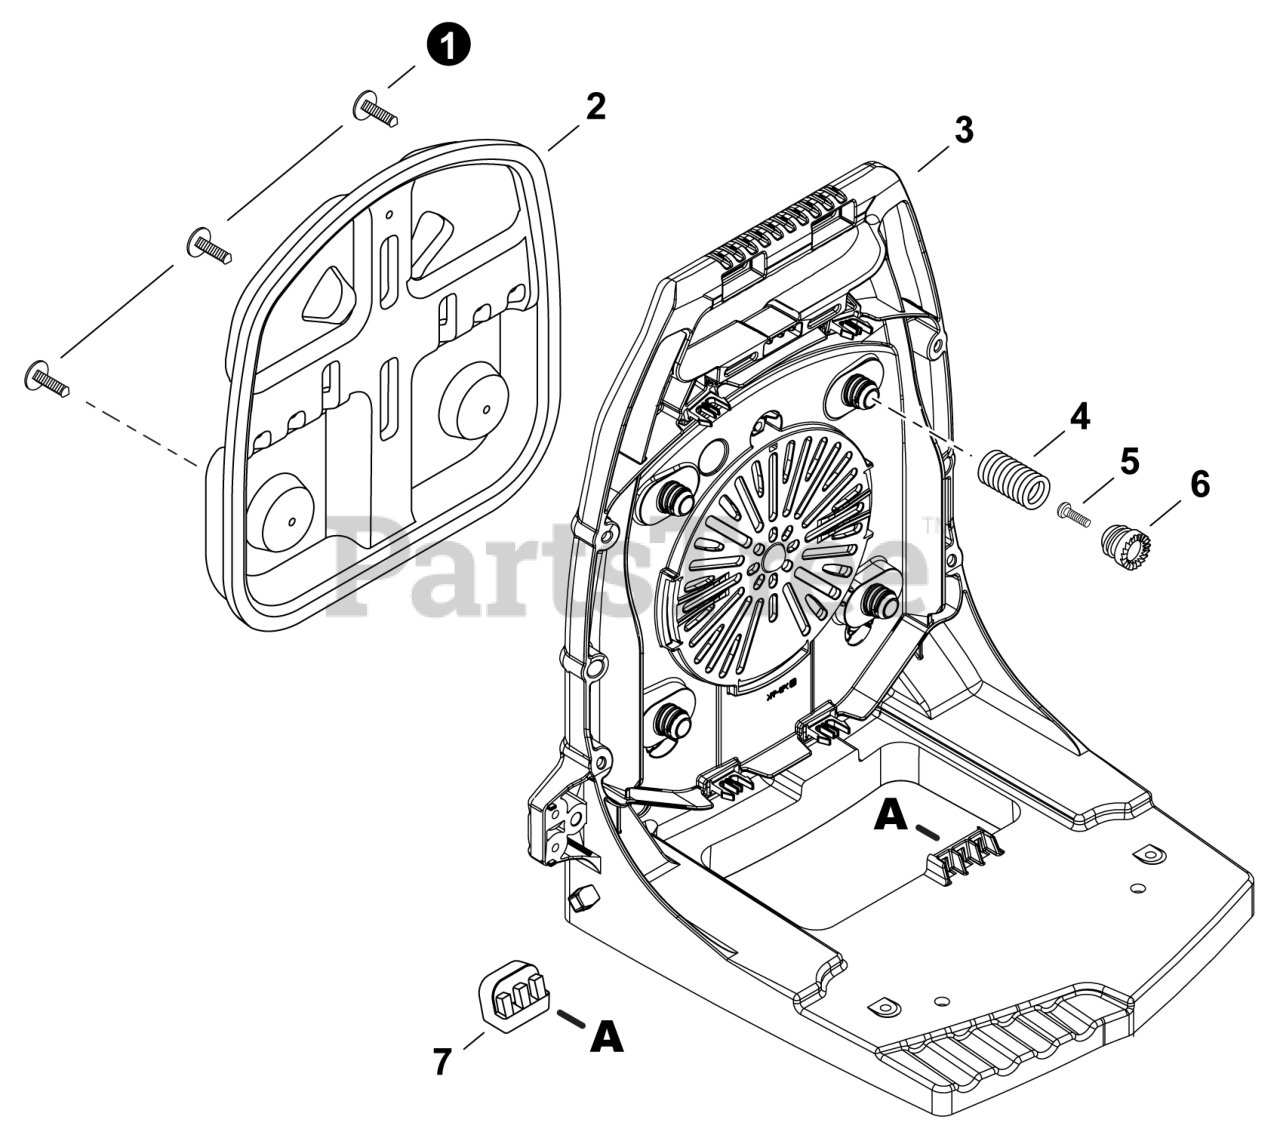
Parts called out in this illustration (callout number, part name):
2	CUSHION, BACKPACK
3	FRAME, BACKPACK
4	SPRING, COMPRESSION
5	BOLT, TORX 5x20
6	HOLDER, SPRING
7	CUSHION
